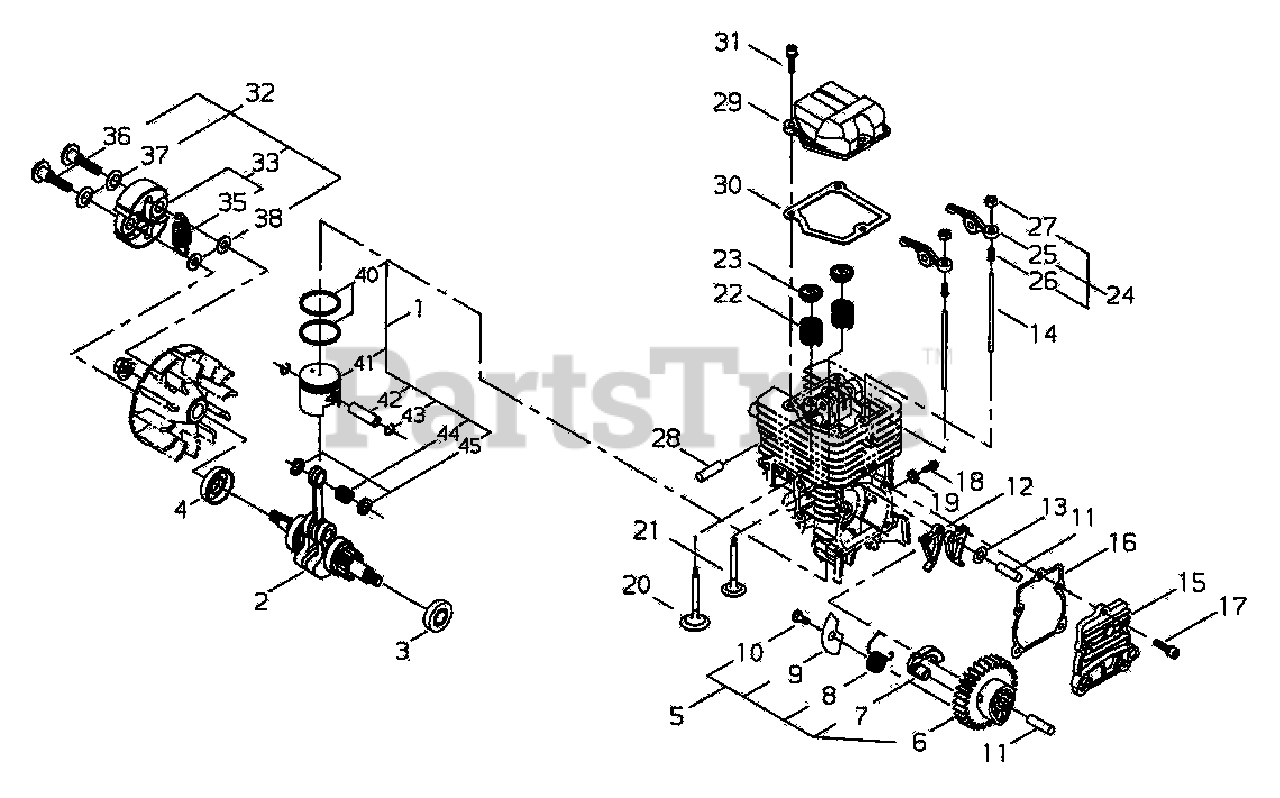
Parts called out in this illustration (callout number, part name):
1	PISTON KIT
2	CRANKSHAFT ASSY
3	SEAL, OIL 12
4	SEAL, OIL 12
5	CAM GEAR ASSY
6	GEAR, CAM
7	WEIGHT
8	SPRING
9	PLATE
10	SCREW, TAPPING 4×6
11	PIN, LOCATING Ø5×29.8 MM
12	FOLLOWER, CAM
13	WASHER 5 MM
14	PUSHROD
15	COVER, CAM GEAR
16	GASKET, CAM GEAR
17	BOLT M4×14
18	SCREW M5
19	WASHER Ø10ר5.5×2
20	VALVE, INTAKE
21	VALVE, EXHAUST
22	SPRING, VALVE
23	VALVE RETAINER ASSY
24	ARM ASSY, ROCKER
25	ARM, ROCKER
26	SCREW, ADJUSTER
27	NUT, ADJUSTER LOCK 5
28	SHAFT, ROCKER ARM Ø5×31.8 MM
29	COVER, ROCKER ARM
30	GASKET, ROCKER ARM
31	BOLT M4×12
32	CLUTCH ASSY
33	SHOE ASSY, CLUTCH
35	SPRING, CLUTCH
36	BOLT, CLUTCH
37	WASHER, SPRING
38	WASHER 6 MM
40	RING, PISTON
41	PISTON
42	PIN, PISTON
43	RING, SNAP
44	BEARING, NEEDLE 9
45	WASHER, THRUST 9
